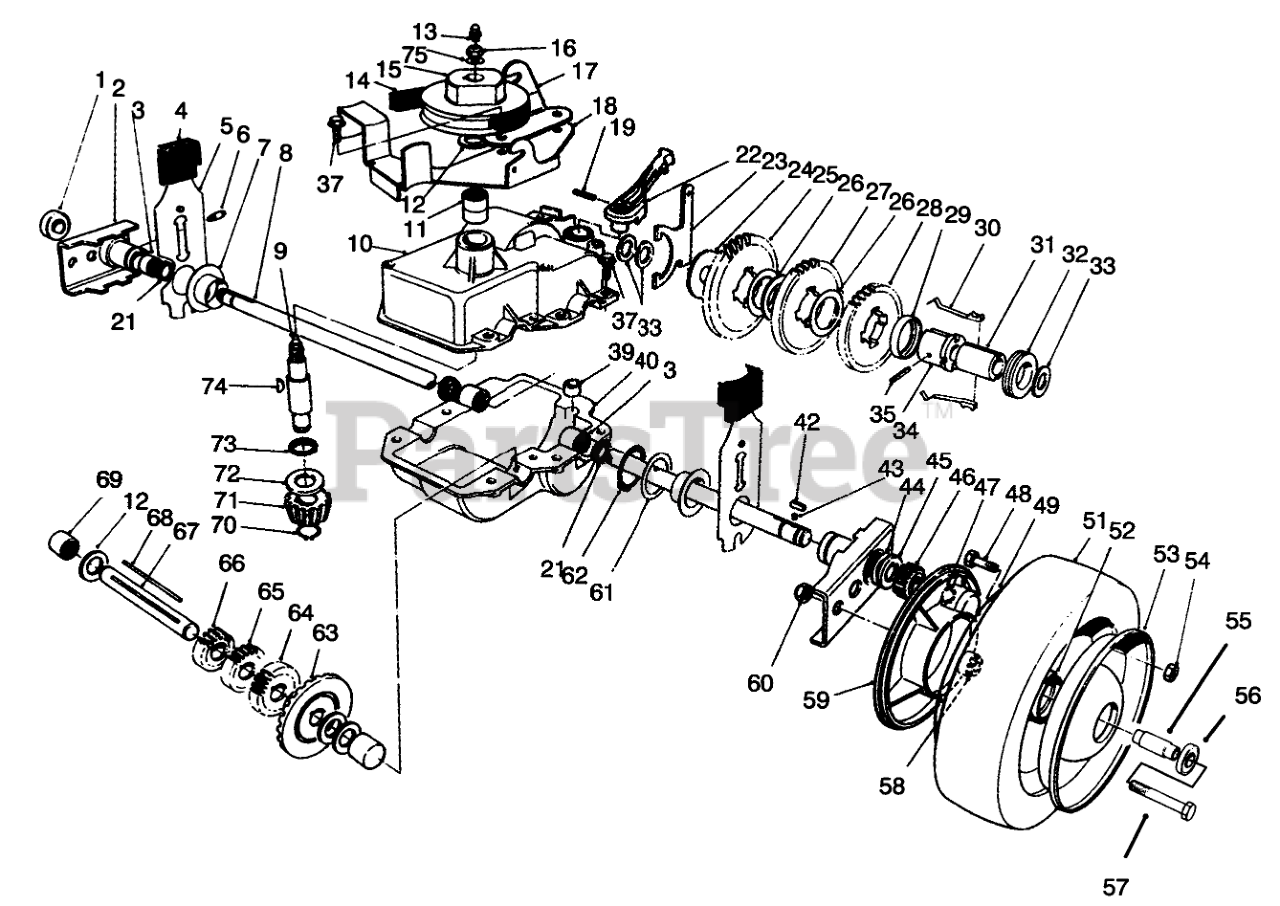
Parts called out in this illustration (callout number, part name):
1	BEARING-WHEEL
2	Pivot Arm Assembly (Incl. Ref. #1, 3, 6 & 21)
3	BEARING-ROLLER
4	KNOB-ARM
5	REAR SPRING ARM ASM
7	CAP-END
8	SHAFT-OUTPUT
9	Shaft-Input (Incl. Ref. #13)
10	Upper Case Assembly (Incl.Ref. #11 & 73)
11	BEARING-NEEDLE
12	WASHER-THRUST
13	FITTING-GREASE, ZERK
14	V-BELT
15	PULLEY
16	NUT-HEX
17	Bracket-Traction Engage
18	Belt Guide Bracket
19	PIN-COIL
21	SEAL-OIL
22	LEVER-SHIFT
23	YOKE-SHIFT
24	WASHER
26	WASHER
27	GEAR-42T
28	GEAR-38T
29	RETAINER-KEY
30	KEY-SHIFT
31	SLEEVE
32	COLLAR-SHIFT
33	WASHER-PLAIN
34	SLEEVE-GEAR
35	PIN-GROOVE
37	SCREW-HWHTF
39	BUSHING-YOKE
40	CASE-GEAR, LOWER
43	SPRING-COMPRESSION
44	WASHER-THRUST, OUTER
45	WASHER-THRUST, OUTER
46	GEAR-PINION
47	RING-RETAINING
48	SCREW-HH
49	Wheel-Half
52	HUB-BEARING
53	Wheel-Half
54	NUT-LOCK, NI
55	SPACER-BEARING
56	BEARING-WHEEL
57	SCREW-HH
58	SPACER-COVER, WHEEL
59	COVER-WHEEL
60	NUT-LOCK, CONE
61	WASHER
62	RING-RETAINING
63	GEAR-BEVEL
64	GEAR-18T
65	GEAR-14T
66	GEAR-12T
67	SHAFT-INTERMEDIATE
69	BEARING-NEEDLE, CLOSED
70	RING-RETAINING
71	PINION-BEVEL
72	WASHER-THRUST
74	KEY-WOODRUFF
75	WASHER-FLAT
